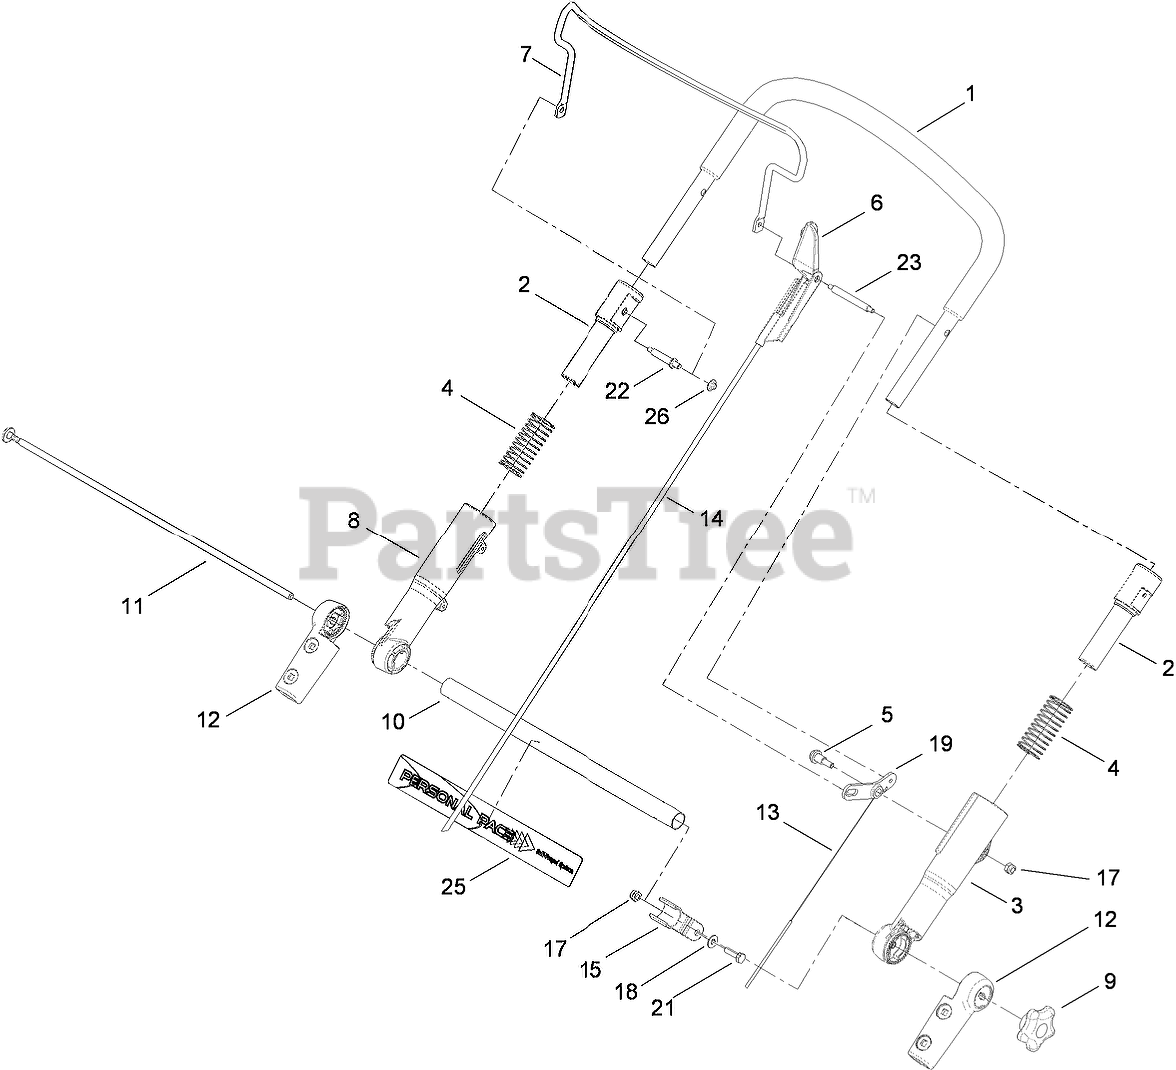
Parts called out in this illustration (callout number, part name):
1	UPPER HANDLE ASM
2	SLEEVE-INNER
3	SLEEVE-OUTER, LH
4	SPRING-COMPRESSION
5	BOLT-SHOULDER
6	STOP-PIVOT
7	BAIL-BRAKE
8	SLEEVE-OUTER, RH
9	KNOB-HANDLE
10	TUBE-CROSS
11	ROD-THREADED
12	MOUNT-HANDLE, LOWER
13	CABLE-TRACTION
14	CABLE-BRAKE
15	CLAMP-CABLE
17	NUT-LOCK, NI
18	WASHER-FLAT
19	LEVER-TRACTION
21	SCREW-HH
22	PIN-HANDLE
23	PIN-BAIL, LH
25	DECAL-PERSONAL PACE
26	RETAINER-PUSH ON
